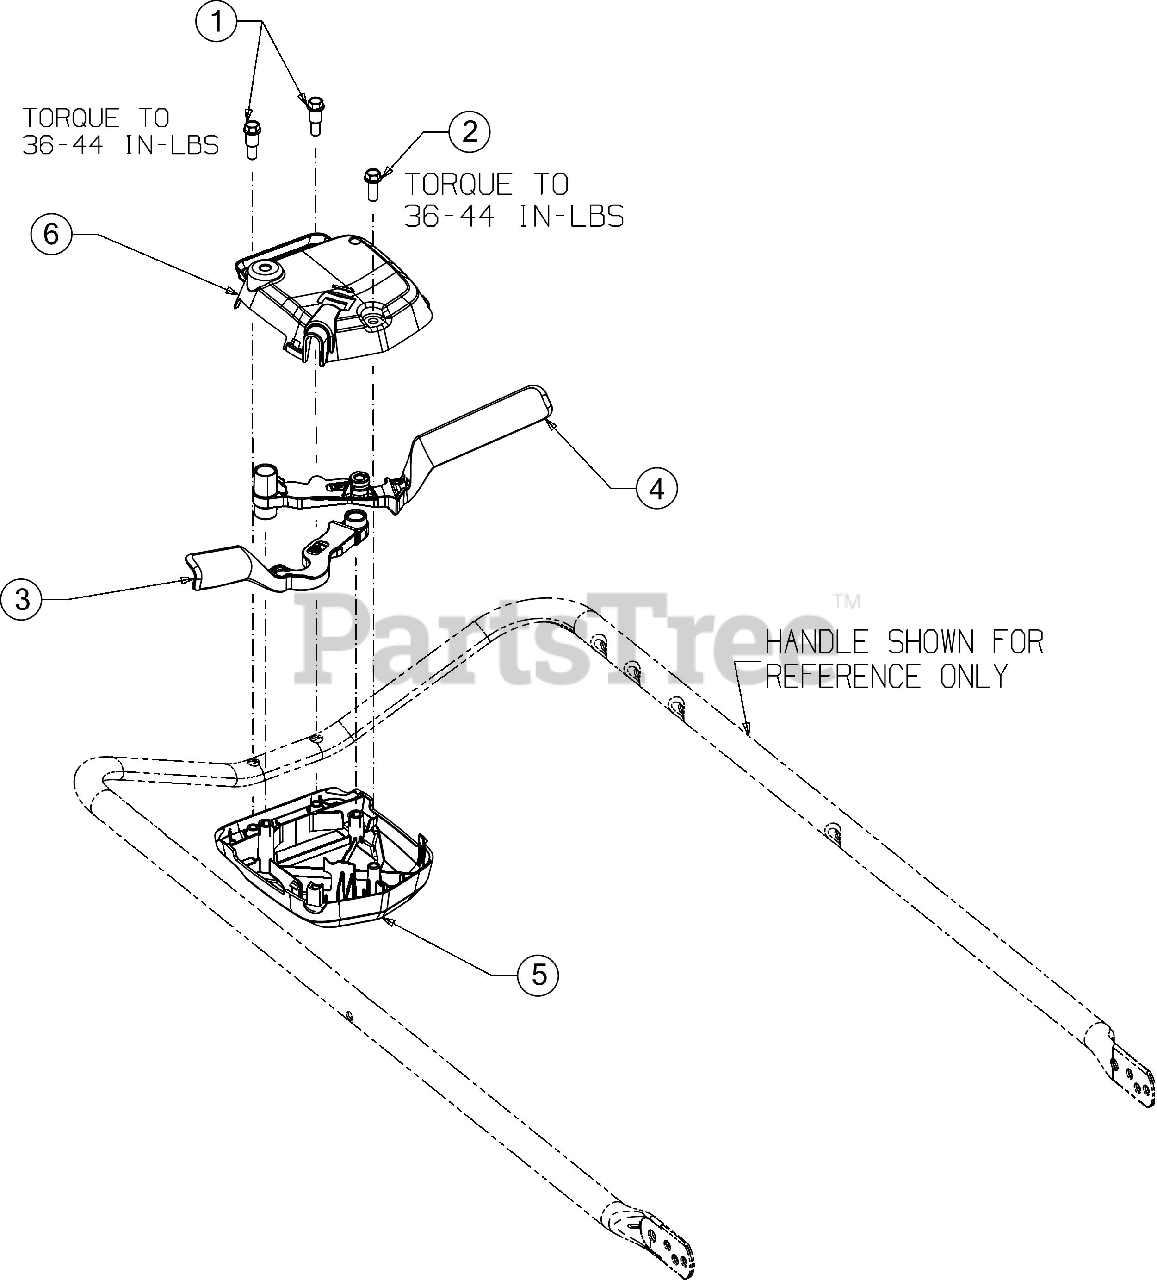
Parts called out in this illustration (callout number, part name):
1	SHOULDER SCREW 1/4-15 x .970
2	SCREW 1/4-15 x .750
3	CONTROL LEVER (LH)
4	CONTROL LEVER (RH)
5	UPPER CONTROL HOUSING
6	LOWER CONTROL HOUSING
